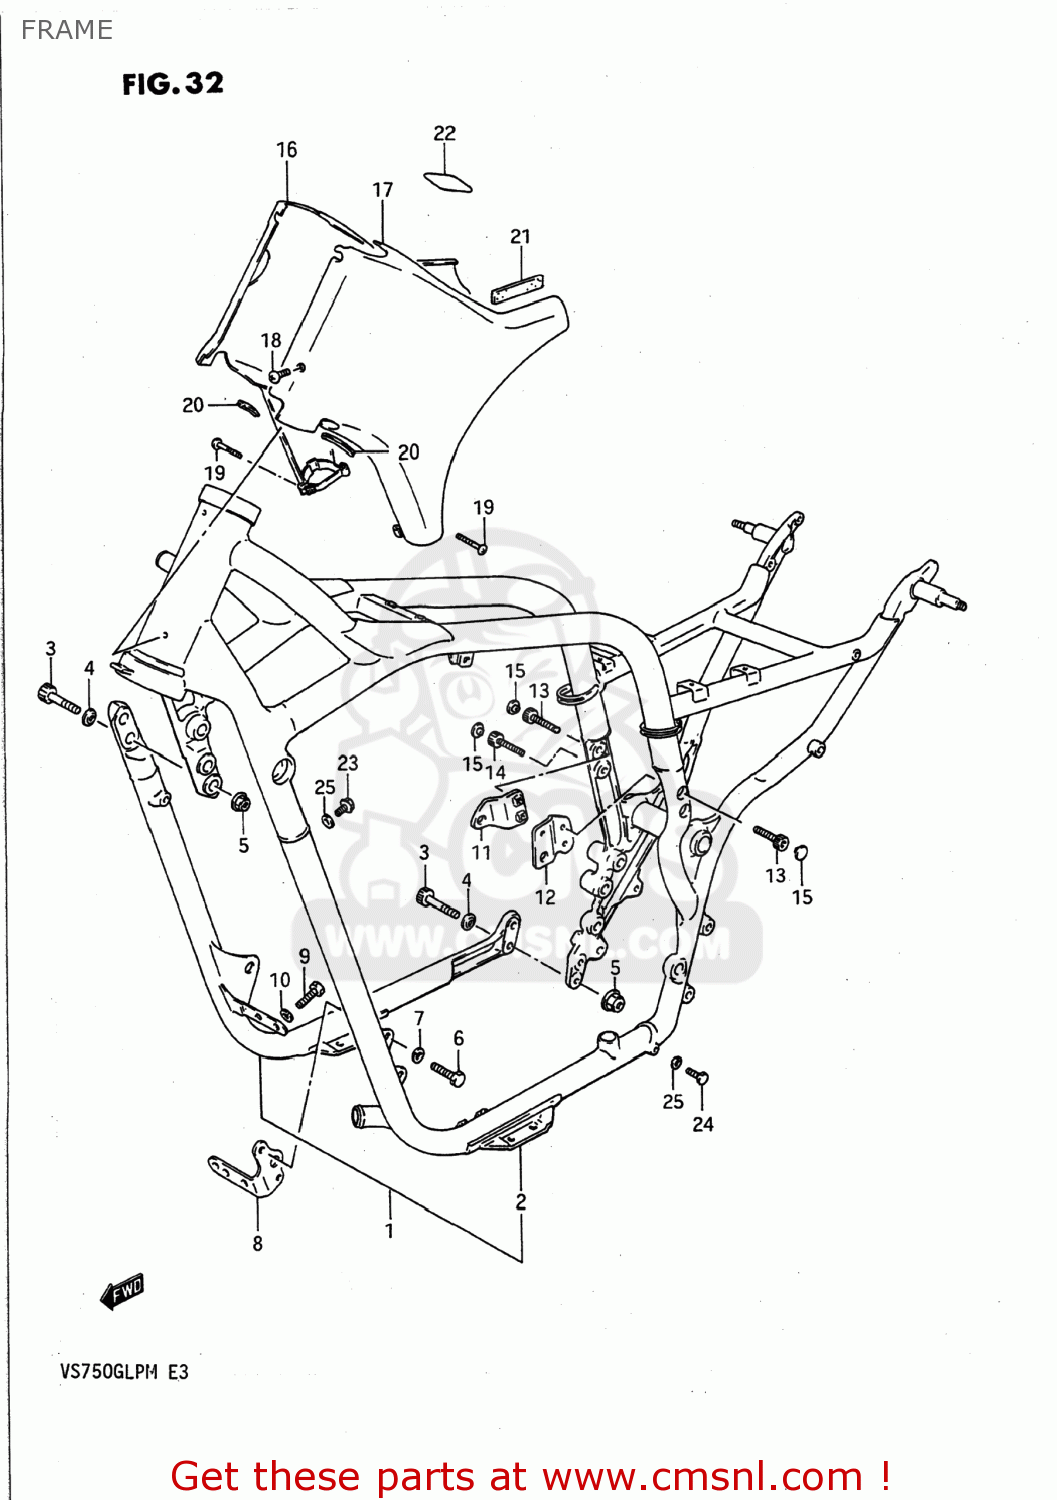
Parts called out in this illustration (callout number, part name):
1	FRAME
2	TUBE COMP,FRAME DOWN,LEFT
3	BOLT(10X33)
4	WASHER
5	NUT 10MM
6	BOLT
7	WASHER,LOCK,8.
8	PLATE,ENGINE MOUNTING
9	BOLT
10	WASHER,LOCK,8.
11	PLATE,ENGINE MOUNTING
12	PLATE,ENGINE MOUNTING
13	BOLT(8X30)
14	BOLT 8X30
15	CAP(OD:14.5)
16	COVER,FRAME HEAD,RIGHT
17	COVER,FRAME HEAD,LEFT
18	SCREW 5X10
19	SCREW
20	MOLDING,FUEL TANK
21	PROTECTOR(20X90)X2
22	TAPE,FRAME HEAD COVER
23	UNION
24	BOLT
25	GASKET(6.2X11X1).2 (NAS)
